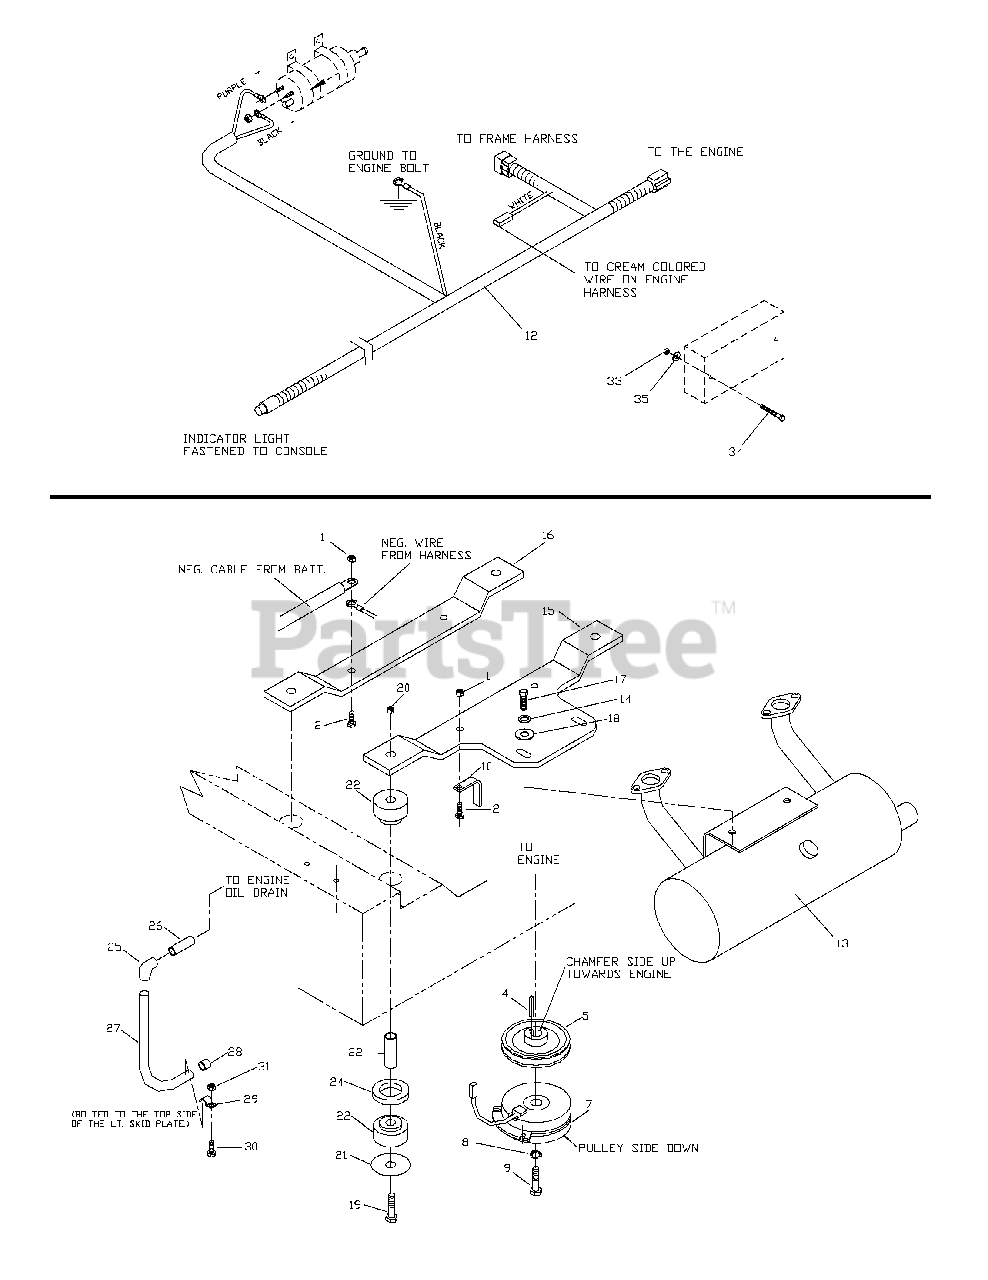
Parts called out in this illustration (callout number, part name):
1	NUT 5/16 LOCK
2	HCS 5/16 X 1.75
4	KEY 1/4 SQ.
8	7/16 LOCK WASHER
9	HCS 7/16F X 2.5
10	CLUTCH TIE DOWN
12	EFI HARNESS
13	EFI MUFFLER
14	5/16 LOCK WASHER
15	REAR ENGINE MT.
16	ENGINE MOUNT
17	HCS 5/16 X 1.0
18	5/16 FLAT WASHER
19	HCS 1/2 X 3.25
20	NUT 1/2 NYLOC
21	ISOLATOR WASHER
24	ISOLATOR SPACER
25	90 DEG. ELBOW
26	PIPE 3/8 X 1.5 NPT
27	OIL DRAIN HOSE
30	HCS 1/4 X 3/4
31	NUT 1/4 LOCK
32	SCREW SELF TAP
33	NUT #10 NYLOC
34	SCREW #10 X 2.0
35	#10 WASHER
